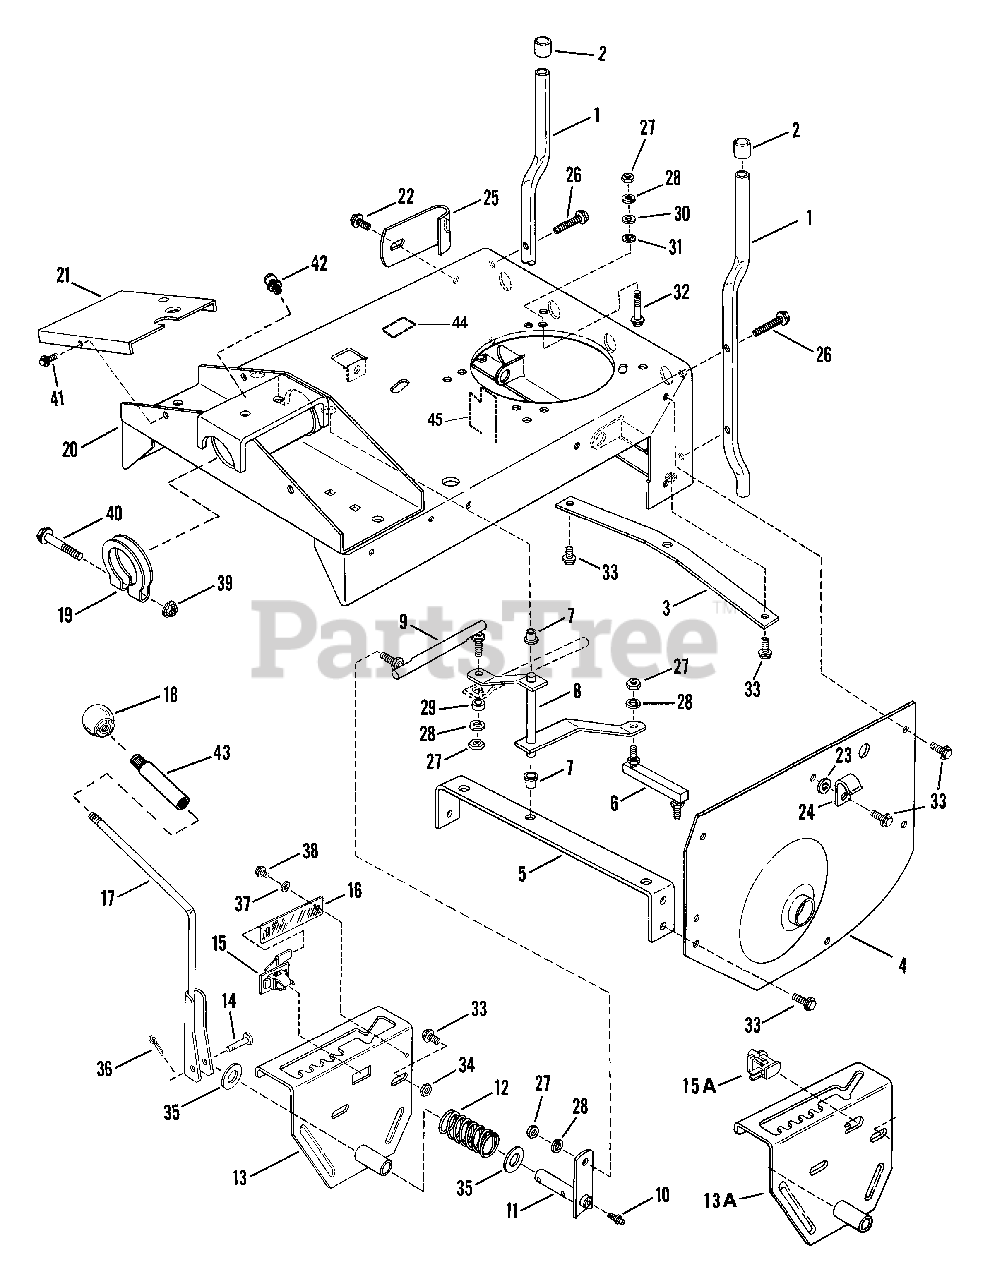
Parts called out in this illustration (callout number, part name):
1	BUMPER, Rear
2	CAP, Bumper
3	PLATE, Hitch
4	FENDER, Left Hand
5	BRACE, Cross
6	LINK, Shift, Short
7	BUSHING, Nylon
8	ARM, Shift
9	LINK, Shift, Long
10	FITTING, Lube (Press fit for .187 hole-no ball)
11	ARM, Shift Handle
12	SPRING, Shift Handle
13	DETENT, Shift ('87 & Earlier Models)
13A	DETENT, Shift ('88 & Later Models)
14	CLEVIS-PIN, 3/8x1 114"
15	SWITCH, Interlock, Assembly ('87 & Earlier Models)
15A	SWITCH, Seat
16	PROTECTOR, Switch ('87 & Earlier Models)
17	HANDLE, Shift
18	KNOB, Shifter BAll
19	CLAMP, Main Tube
20	MAIN CASE
21	PANEL, Switch
22	SCREW, 5/16-18x3/4" Self-Tapping
23	WASHER, 5/16 Internal Tooth
24	CLIP, Wiring
25	SUPPORT, Bumper
26	SCREW, Self-Tapping, 5/16-18x1 1/2"
27	NUT, 5/16-24 Hex
28	WASHER, 5/16 Split Lock
29	ROLLER
30	WASHER, 5/16 Flat
31	RETAINER, Bolt
32	SCREW, 5/16-24x1 1/2" Hex Cap
33	SCREW, 5/16-18x5/8" Self-Tapping
34	NUT, 5/16-18 Hex
35	WASHER, Thrust
36	PIN, 3/32x3/4" Cotter
37	WASHER, #10 Flat ('87 & Earlier Models)
38	SCREW, #10-24 x 1/2" Hex Washer Self-Tap (Torx)
39	NUT, 5/16-24 Hex Flange Lock
40	SCREW, 5/16-24x2 1/2" Hex Cap
41	SCREW, 1/4-20x1/2" Self-Tapping
42	FITTING, Lube
43	EXTENSION, Shift
44	PAD, Rubber
45	BELT GUIDE (Weldable)
